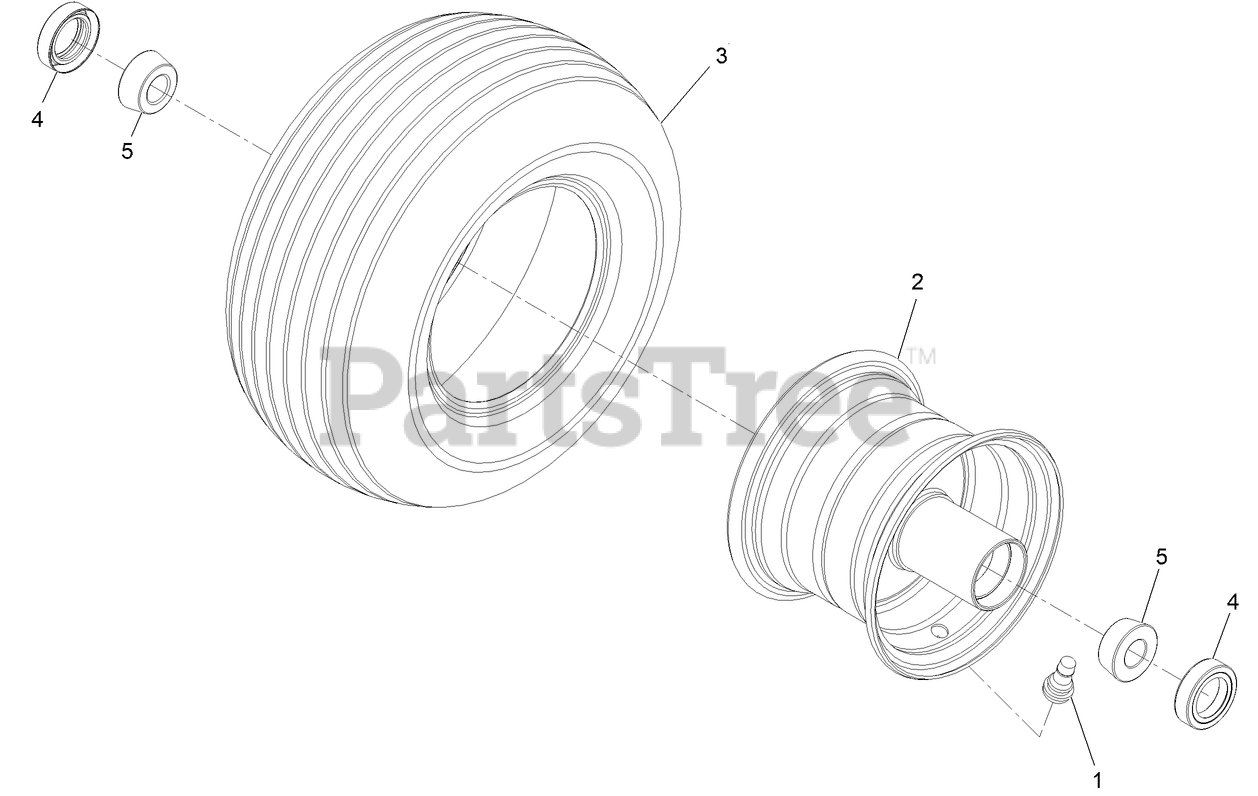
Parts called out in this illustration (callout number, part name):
1	VALVE
2	Rim-6 X 4.5
3	Tire-Rib
4	SEAL-CASTER
5	BEARING-CONE, TAPERED ROLLER
